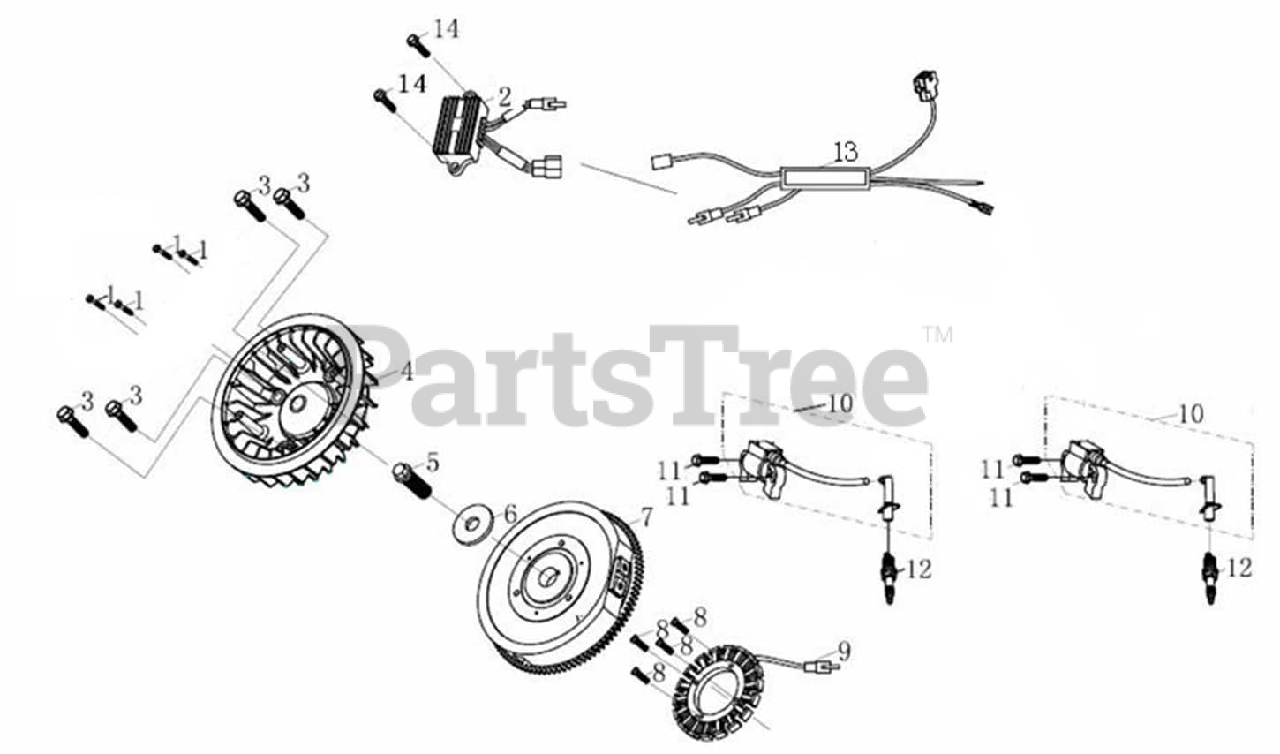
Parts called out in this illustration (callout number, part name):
1	HEXAGON BOLT WITH FLANGE
2	RECTIFIER
3	HEXAGON BOLT WITH FLANGE
4	IMPELLER
5	HEXAGON BOLT WITH FLANGE
6	FLAT WASHER
7	FLYWHEEL COMP
8	SOCKET HEAD SCREW
9	COMPS OF CHRGNG CURRNT ARMATUR
10	COIL ASSY.,IGNNTION
11	BOLT, FLANGE
12	PLUG, SPARK
13	CONNECTING WIRE
14	BOLT, FLANGE
